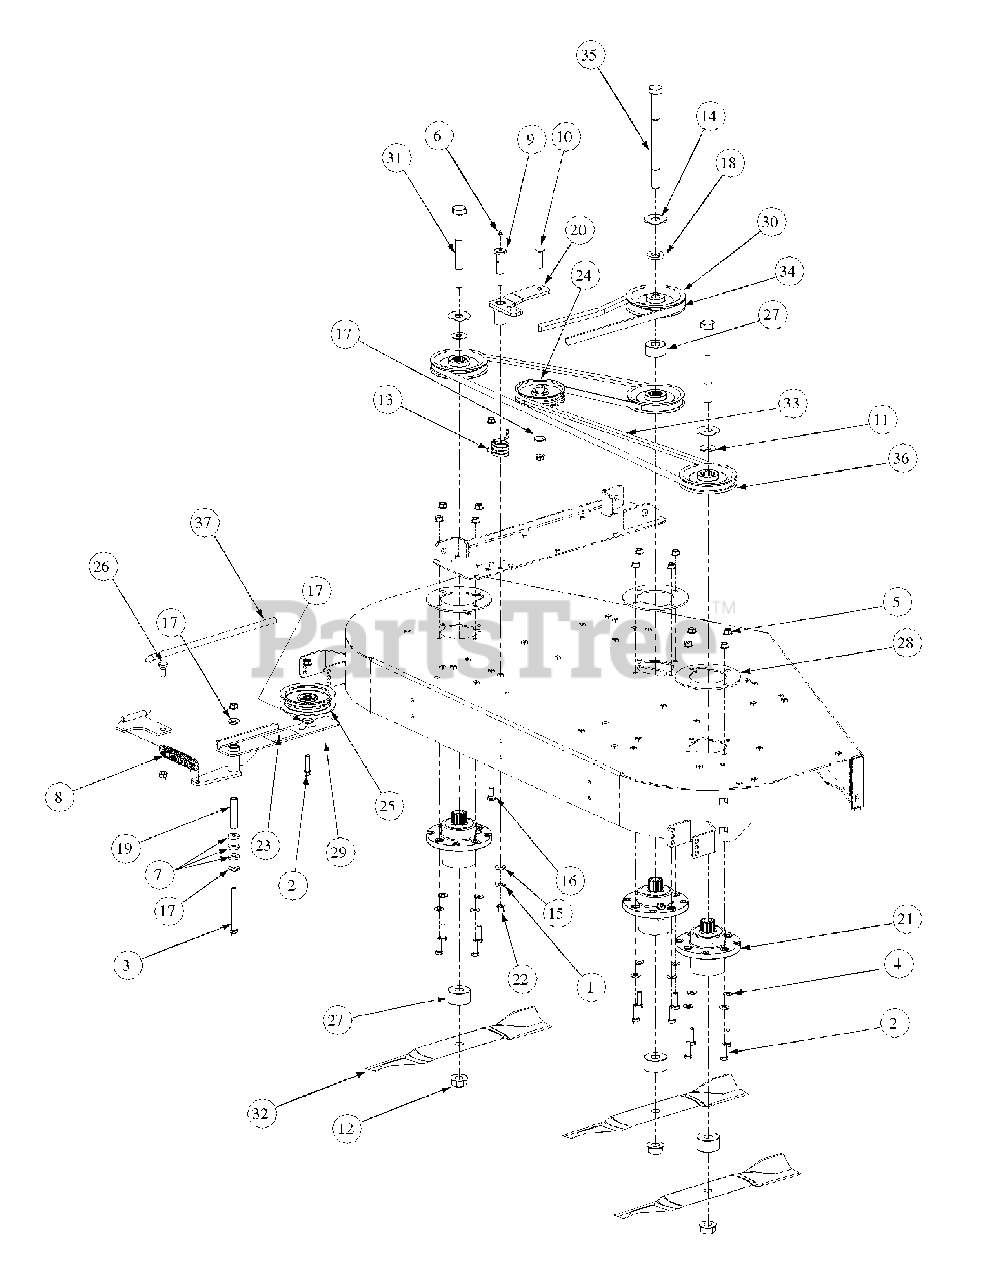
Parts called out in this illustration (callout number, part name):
1	Lock Washer, 7/16
2	Hex Cap Screw, 3/8-16 x 1-1/4
3	Hex Cap Screw, 3/8-16, 4.00
4	Flat Washer, 3/8
5	Hex Nut, Flange Lock, 3/8-16
6	Grease Fitting, 1/4-28 x 3/16
7	Idler Washer
8	Extension Spring, 1.0 OD x 5.125
9	Shoulder Screw, 7/16-14
10	Hex Carriage Screw, 3/8-16, 1.75
11	Spacer, .812 ID x .218 LG
12	Flange Hex Nut, 3/4-16
13	Torsion Spring Idler
14	Flat Washer, .781 ID, 2.00 OD, .105
15	Flat Washer, .469 ID, .875 OD, .105
16	Carriage Bolt, 3/8-16 x 1
17	Flat Washer, .406 ID, 1.0 OD, .105
19	Spacer, .39 ID x .625 OD x 2.75
20	Idler Arm Assembly, Deck Spindle
20	Bearing
21	Spindle Assembly, Aluminum Fab Deck
22	Hex Nut, 7/16-14
23	Decal, Idler Location
24	Flat Pulley
25	Idler Pulley, 4.06 OD w/Deep Plan Flanges
26	Shoulder Screw, .50 x .27 LG, 3/8-16
27	Spacer, .760 ID x 2.000 OD x 1.1
28	Plate Support, Cast Aluminum Spindle
29	Idler Arm Assembly, Flat Top Bearing
30	V Pulley, 5.25 OD
31	Hex Cap Screw, 3/4-16, 7.00
32	Hi-Lift Blade, 19.0, 0.756
33	V Belt, A Section x 114.3
34	V Belt, B Section x 87.3
35	Hex Cap Screw, 3/4-16, 9.00
36	V Pulley, 5.00 OD
37	Rod Fab Deck Spring Tension
